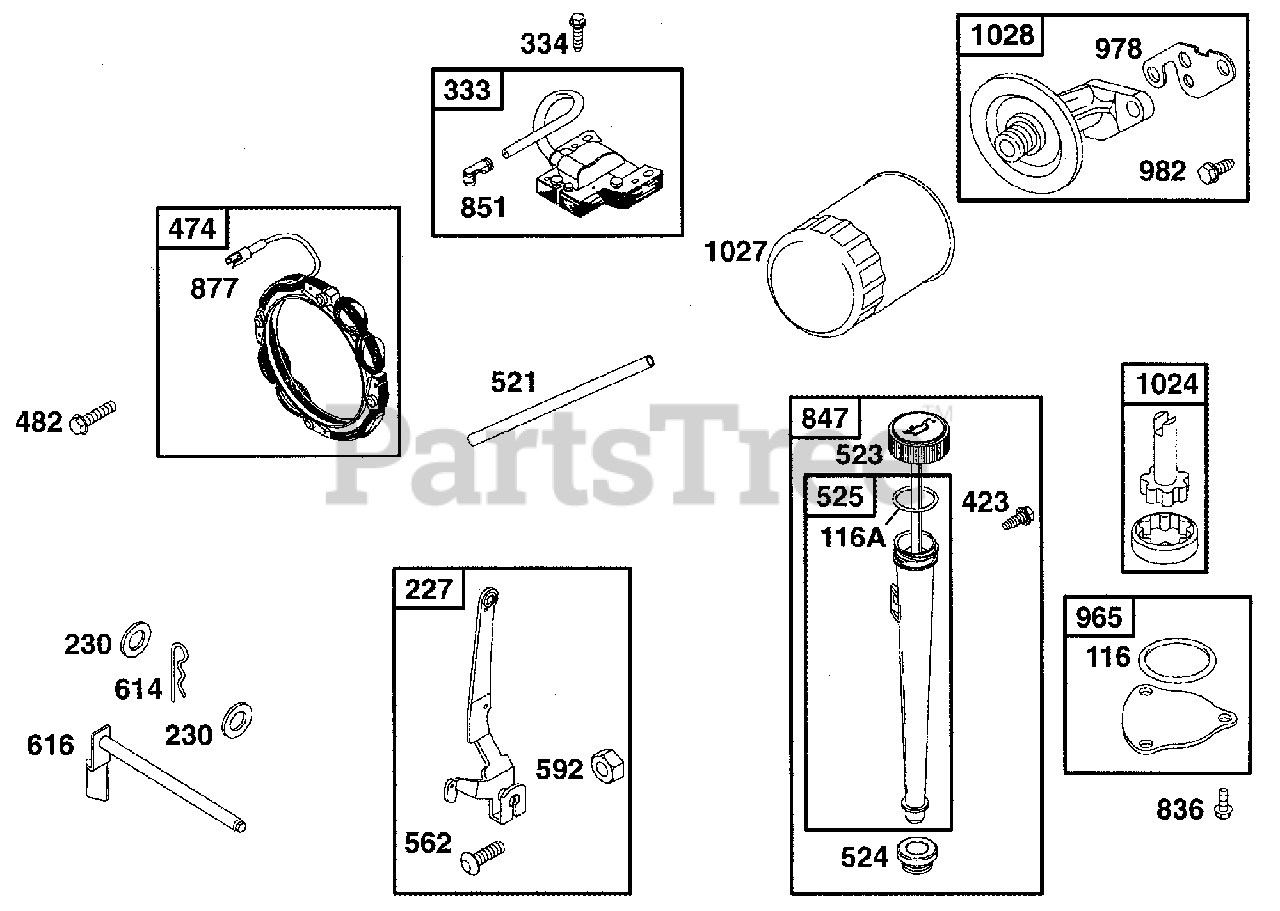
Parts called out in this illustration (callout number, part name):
116	Seal-O-Ring
116A	Seal-O-Ring
227	Governor Lever
230	Flat Washer
333	Magneto Armature
334	Hex Screw
423	Shoulder Screw
474	Alternator
482	Hex Screw
521	Cable Shield
523	Dipstick
524	Fill Tube Seal
525	Oil Fill Tube
562	Governor Lever Bolt
614	Cotter Pin
616	Governor Crank
836	Hex Screw
847	Dipstick/Tube Assembly
851	Cable Terminal
877	Alternator Wire
965	Pump Cover
978	Oil Adapter Gasket
982	Hex Screw
1027	Oil Filter
1028	Filter Adapter
